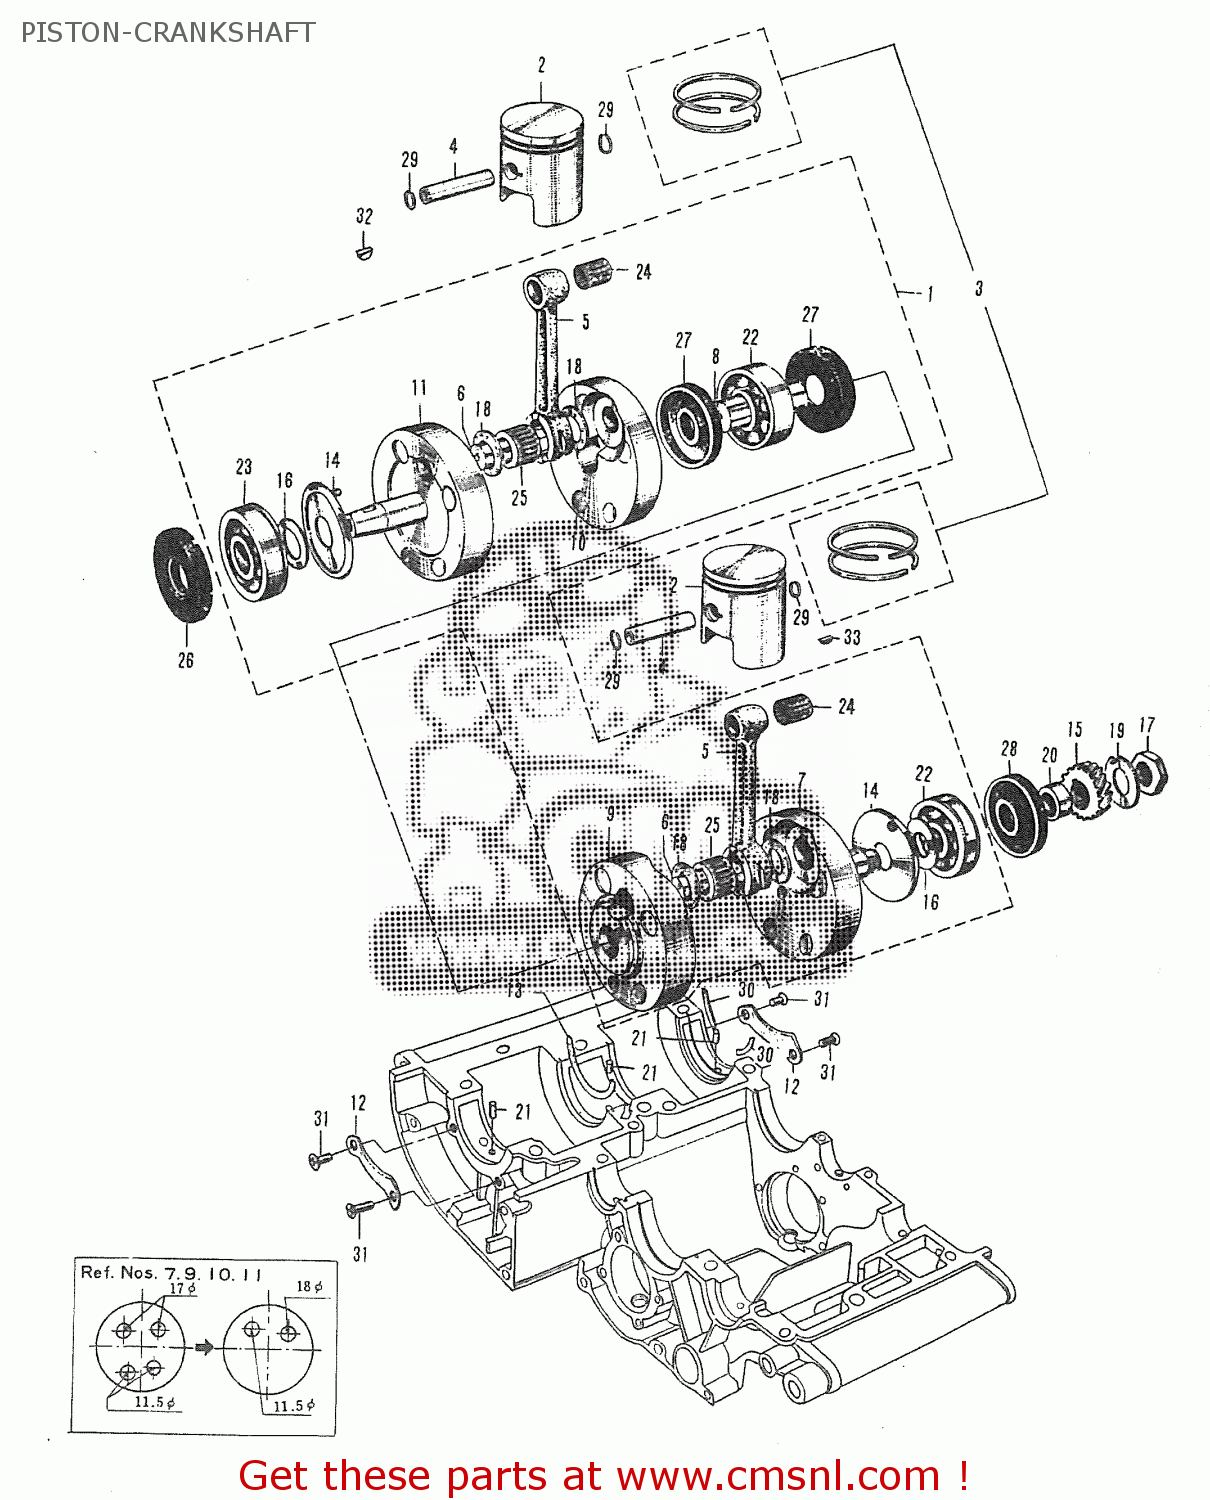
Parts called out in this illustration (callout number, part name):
1	CRANKSHAFT ASS'Y
2	PISTON
3	RING SET,PISTON
4	PIN,PISTON
5	CONNECTING ROD
6	PIN,CRANK
7	RIGHT CRANKSHAFT
9	RIGHT CRANK WHEEL
10	LEFT CRANK WHEEL
11	LEFT CRANKSHAFT
12	CRANKSHAFT OIL SEAL POSITIONING PIECE
13	CENTER CRANKSHAFT OIL SEAL POSITIONING PIECE
14	OIL GUIDE PLATE
15	PRIMARY PINION
16	CRANKSHAFT THRUST WASHER
17	PRIMARY PINION NUT
18	WASHER (20X34X1)
19	PRIMARY PINION WASHER
20	PRIMARY DRIVE GEAR SPACER
21	ROLLER(4X13.8)
22	BALL BEARING
23	CENTER CRANKSHAFT BEARING
24	BEARING
25	BEARING
26	OIL SEAL
27	OIL SEAL CENTER
28	SEAL,OIL
29	RING,SNAP 14MM
30	RIGHT CRANKSHAFT BEARING POSITION PIECE
31	CROSS HEAD SCREW
32	KEY
33	KEY
